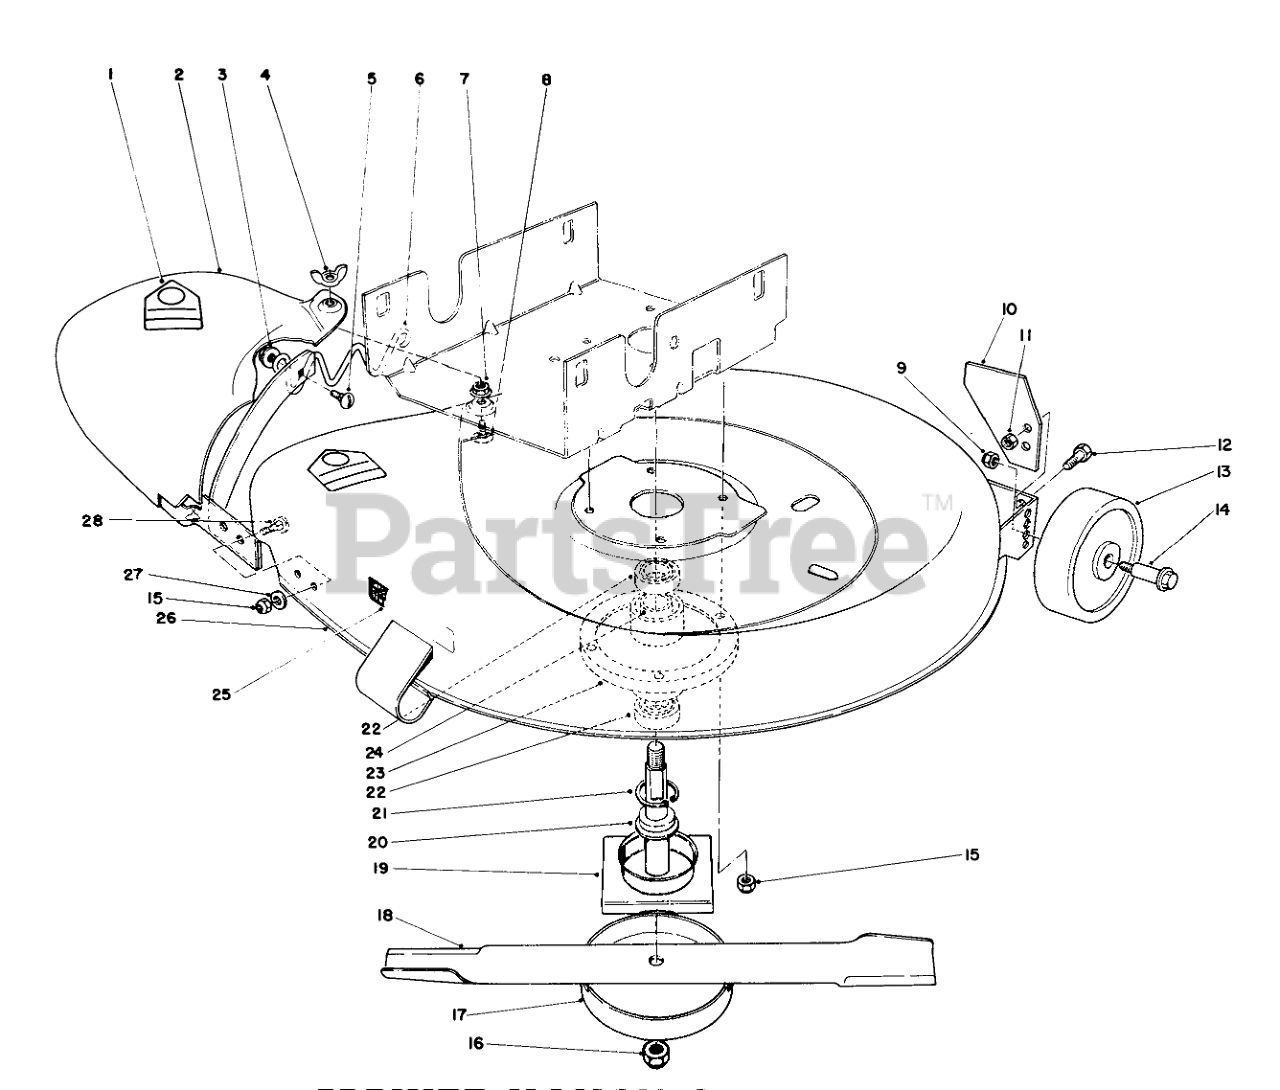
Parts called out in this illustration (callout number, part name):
1	DECAL-DANGER
2	DEFLECTOR WA R
3	NUT-LOCK, HHF
4	Wing Nut
5	SCREW-CARRIAGE
6	FOOT GUARD BRKT
7	PAL NUT
8	Carriage Bolt
9	NUT-LOCK, NI
10	Deck Stop
11	NUT-LOCK, CONE
12	SCREW-HH
13	DECK WHEEL
14	BOLT-WHEEL
15	NUT-LOCK, NI
17	Cup
18	Blade
19	Shaft-Spindle
20	SPINDLE SPACER
21	RING-RETAINING
22	BEARING-BALL
23	Spindle Hub
24	SPACER-BEARING
25	Decal-Deck Inst.
26	HOUSING WA R
27	WASHER-FLAT
28	BOLT-CARR
